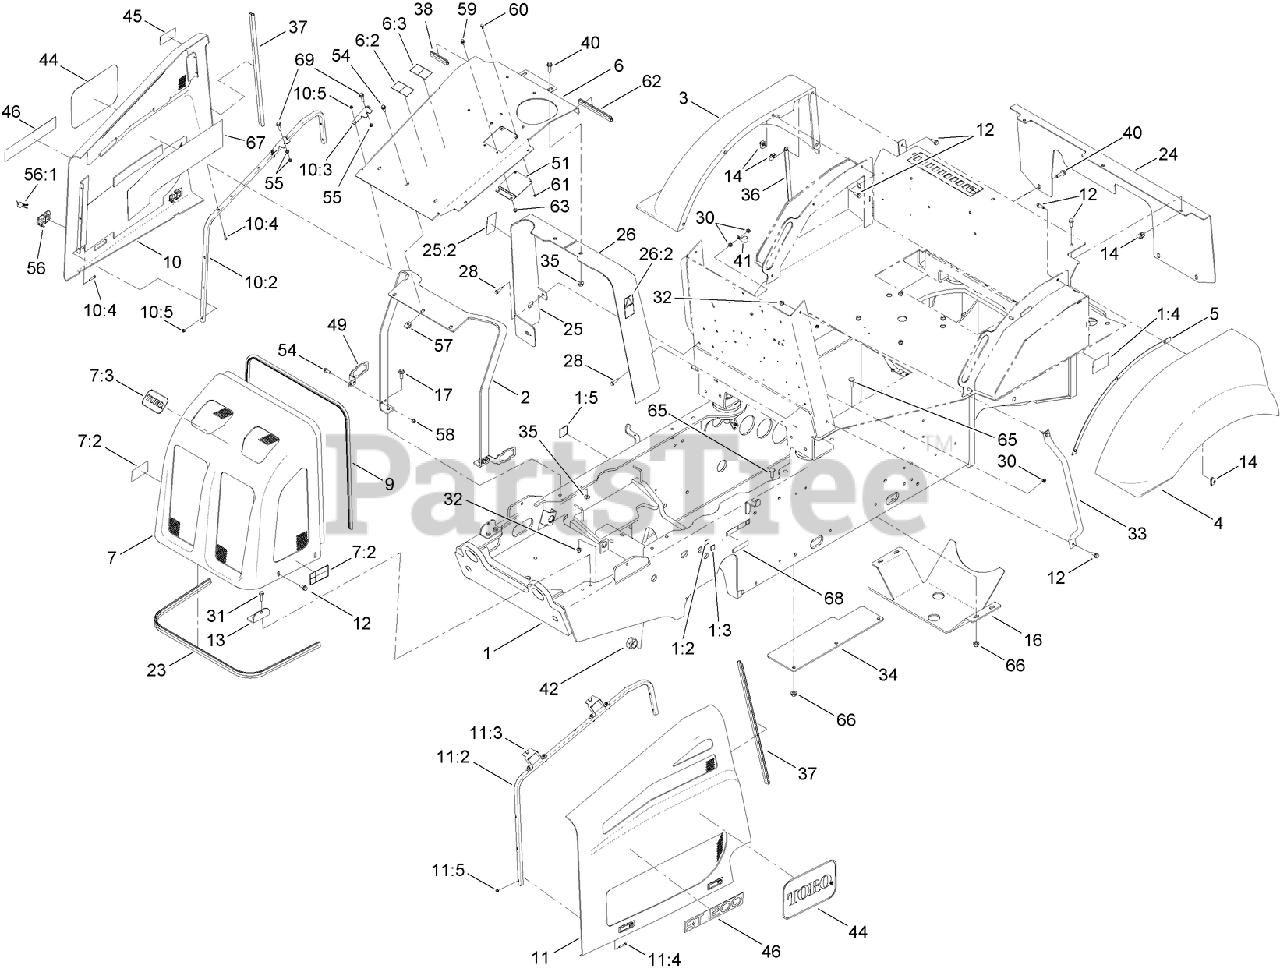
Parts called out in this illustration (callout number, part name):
1	MAIN FRAME ASM
1:2	DECAL-FLUID, HYDRAULIC (OUT)
1:3	DECAL-FLUID, HYDRAULIC (IN)
1:4	DECAL-LIFT/TIE DOWN
1:5	DECAL-DRAIN, OIL
2	SUPPORT-HOOD
3	FENDER-RH
4	FENDER-LH
5	SUPPORT-FENDER
6	HOOD PLATE ASM
6:2	DECAL-SURFACE, HOT
6:3	DECAL-WARNING, RADIATOR
7	FRONT HOOD ASM
7:2	DECAL-WARNING, FAN
7:3	DECAL
9	SEAL-HOOD
10	RH HOOD ASM
10:2	TUBE-BENT
10:3	BRACKET-HOOD
10:4	SCREW-HH
10:5	NUT-FLANGE, NI
11	LH HOOD ASM
11:2	TUBE-BENT
11:3	BRACKET-HOOD
11:4	SCREW-HH
11:5	NUT-FLANGE, NI
12	SCREW-HHF
13	SUPPORT-COVER, ENGINE
16	PLATE-SKID
17	SCREW-HHF
23	SEAL-BOTTOM, NOSE
24	PLATE-COVER, REAR
25	SUPPORT MOUNT ASM
25:2	DECAL-WARNING, NO RIDERS
26	SUPPORT MOUNT ASM
26:2	DECAL-WARNING, NO RIDERS
28	SCREW-HHF
30	NUT-LOCK, HHF
31	SCREW-HHF
32	NUT-LOCK, NI
33	HANDLE-OPERATOR
34	PLATE-SKID
35	NUT-LOCK, HHF
36	PLATE-REINFORCEMENT, FENDER
37	SEAL-HOOD
38	SEAL-HOOD
40	SCREW-HHF
41	CLAMP-R
45	DECAL-SURFACE, HOT
49	PLATE-BENT
51	COVER ASM
54	SCREW-HHF
55	NUT-HEX
56	LATCH-TRIGGER, RAISED (W/LOCK)
56:1	KEY-REPLACEMENT
57	NUT-CLIP, U
58	NUT-HEX FLG
59	SCREW-HHF
60	SCREW-HHF
61	NUT-RETAINER
62	SEAL-HOOD
63	NUT-HF
65	SCREW-CARR
66	NUT-LOCK
67	FOIL-HEAT
68	DECAL-ARRESTER, SPARK
69	SCREW-HHF
